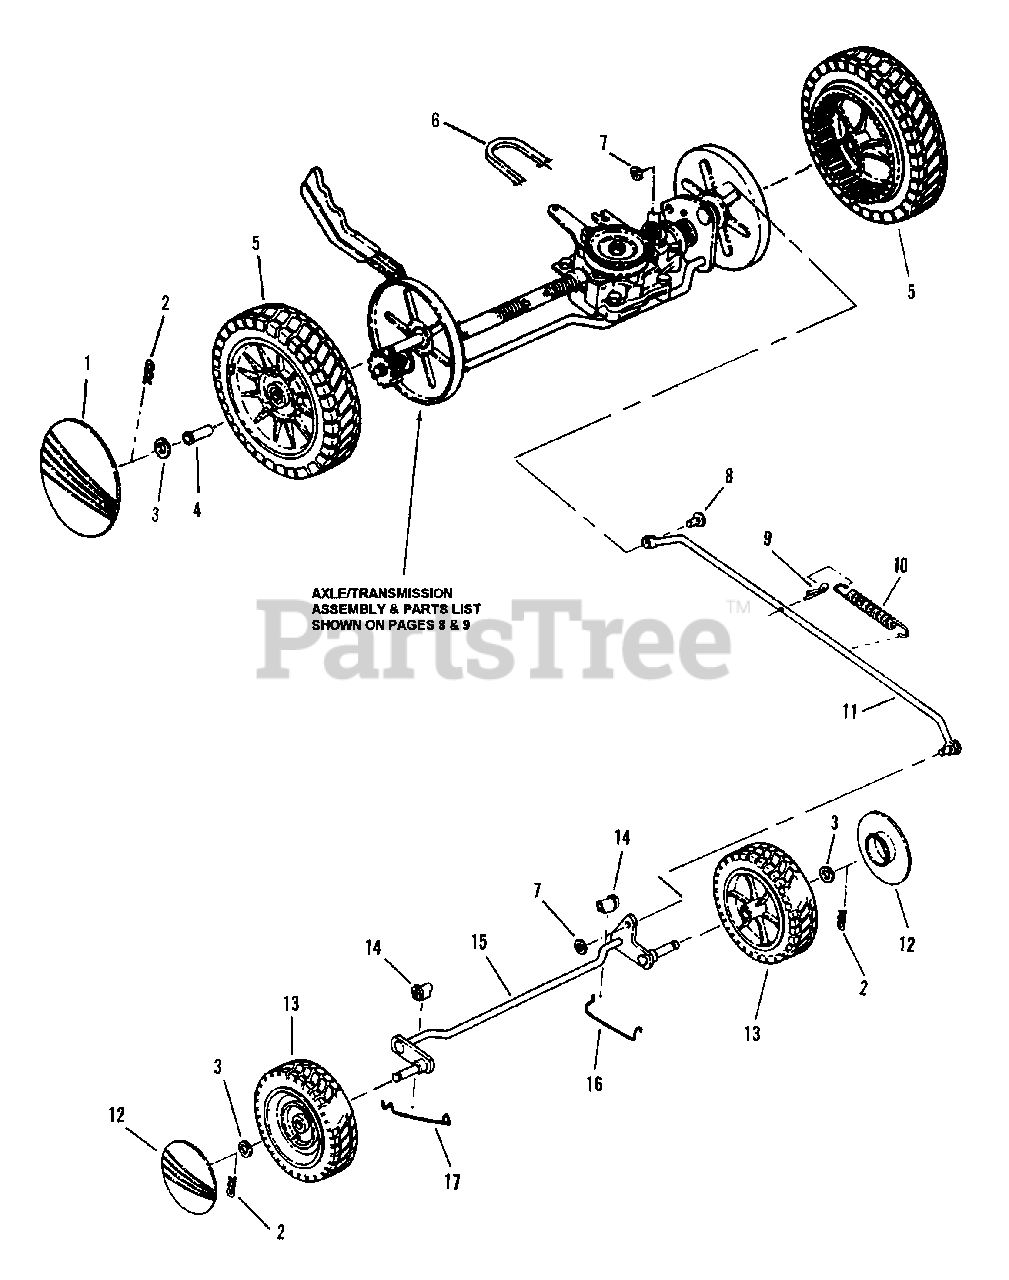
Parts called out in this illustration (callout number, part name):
1	HUB-CAP, Rear Wheels
2	HAIRPIN, 1/16 x 29/32"
3	WASHER, 1/2" Flat
4	BUSHING, Rear Wheel
5	ASSEMBLY, Rear Drive Wheels
6	BELT, Traction Drive
7	RETAINER, Wheel
8	PIN, 3/8 x 5/8" Tie Bar
9	COTTER-PIN, 1/8 x 3/4"
10	SPRING, Tie Bar
11	ASSEMBLY, Tie Bar
12	HUB-CAP, Front Wheels
13	ASSEMBLY, Wheels (Front)
14	BUSHING, Front Axle
15	ASSEMBLY, Front Axle
16	SPRING, Axle Retaining (Left Side)
17	SPRING, Axle Retaining (Right Side)
